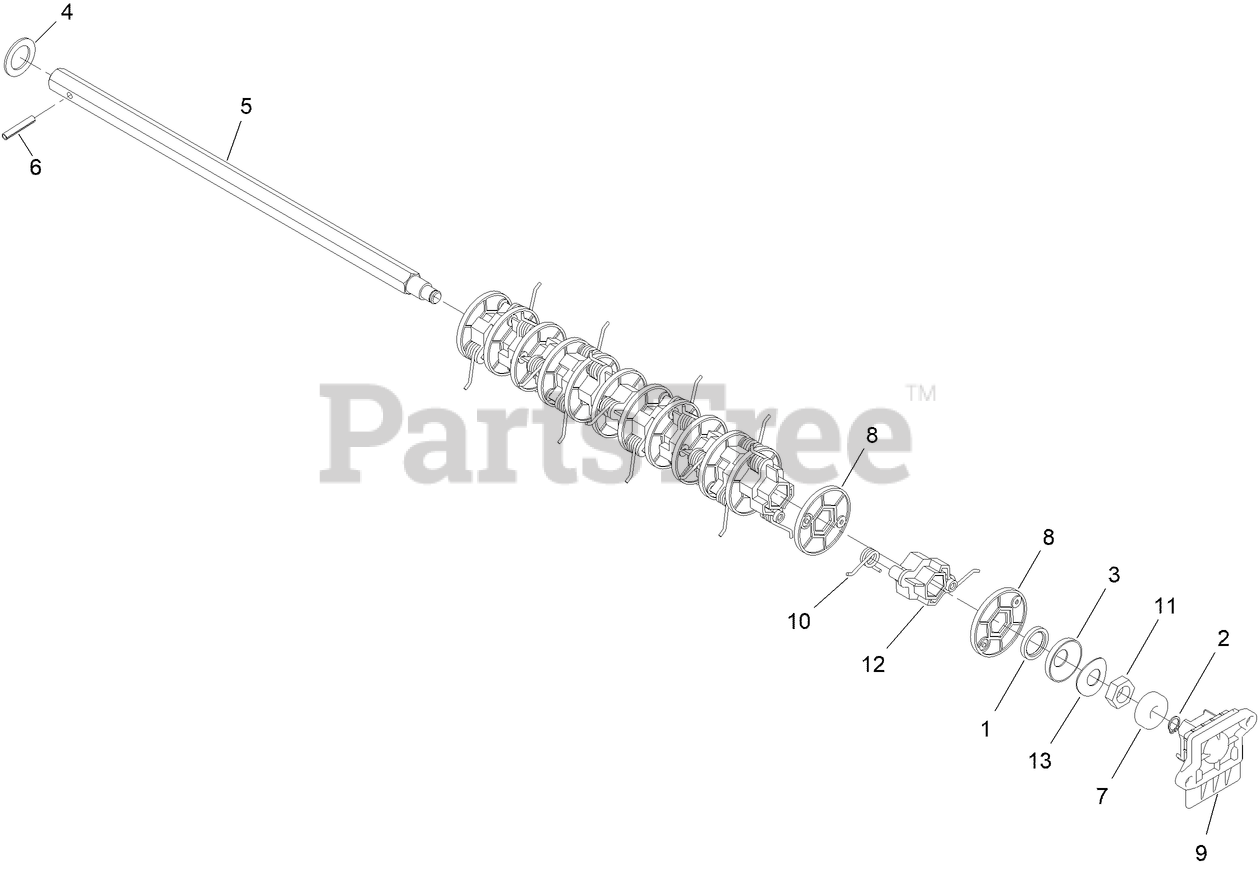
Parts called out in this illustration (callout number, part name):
1	SPACER
2	CIRCLIP
3	SHOULDER PIECE
4	WASHER
5	ROD-HEX
6	PIN-DOWEL
7	BEARING
8	DIVIDER-SPRING, PLASTIC AERATOR
9	BEARING HOUSING V2
10	SPRING TINE V2
11	NUT-HEX
12	SPRING RETAINER, AERATOR
13	WASHER-WAVE
